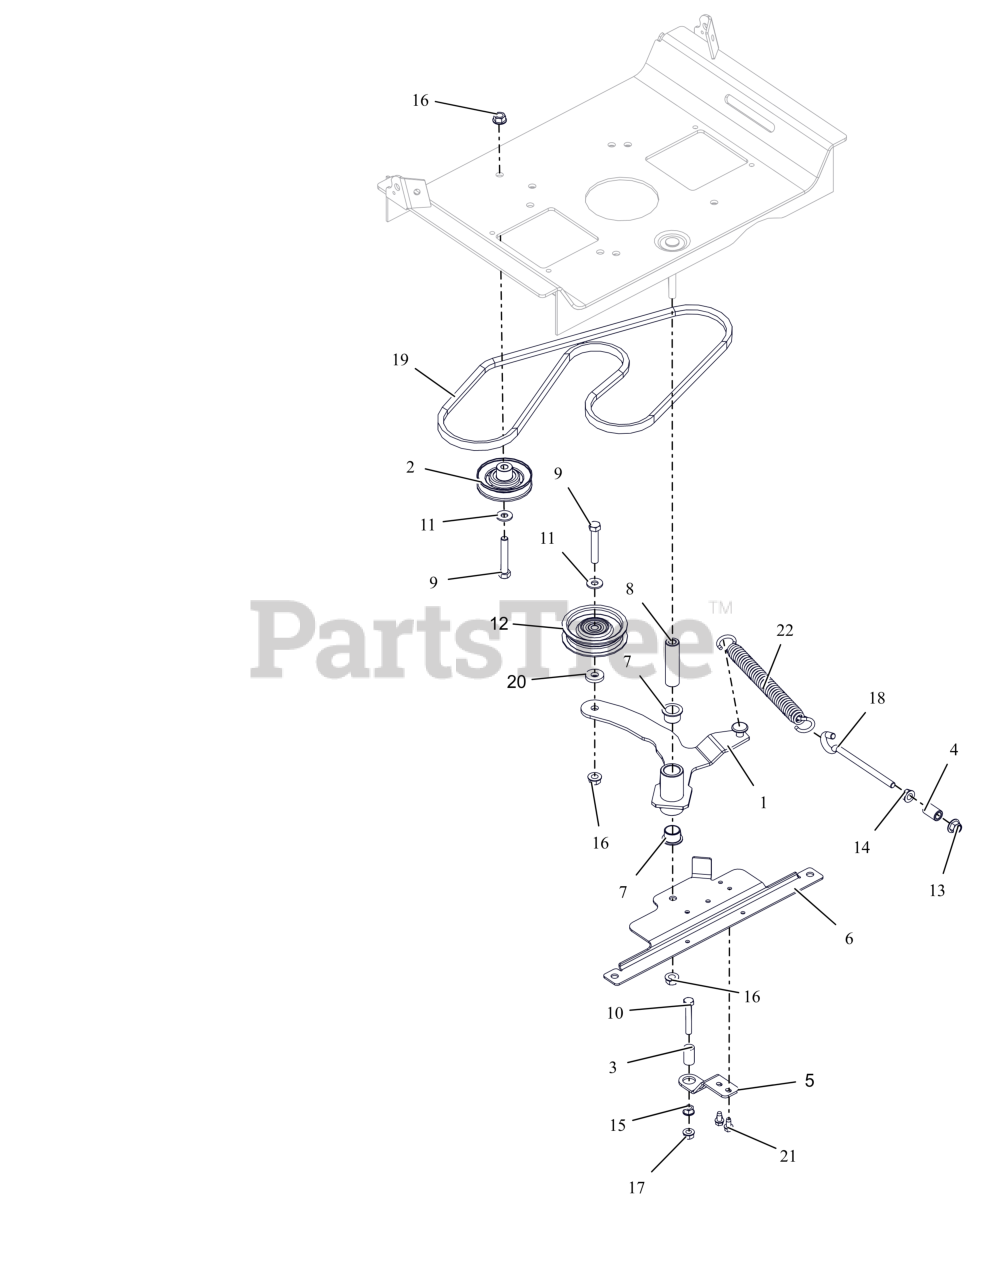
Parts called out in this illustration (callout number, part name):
1	WLDMT,GRD DRIVE IDLER ARM-LGR
2	IDLER, V-3.000 OD
3	SPACER, RUBBER 5/16 IDX1.0 LG
4	SPACER, .375X.625X.970 (PM)
5	BRKT, CLUTCH STOP (XL)
6	BRKT-IDLER ATTACHMENT
7	BSHG-FLG 0.75X0.875X.625X1.125
8	BUSHING, SLEEVE .38X.750X2.78
9	BLT,HEX .38-16X2.25 G5 ZCC
10	BLT, HEX .31-18X2.00 G5 ZCC
11	WSHR,FLT .375X.875X.083 ZCC
12	SHEAVE, IDLER -V .38 x 4.00
13	NUT,NYL-FLG .38-16 GF ZCC
14	NUT, SPNLK-FLG .38-16 G5 ZCC
15	NUT,SPNLK-FLG .31-18 G5 ZCC
16	NUT-LK-TOP-FLG .38-16 ZC120
17	NUT-LK-TOP-FLG .312-18 GF ZCC
18	BOLT,.38-16 X 4.25-.62 DIA EYE
19	V-BELT, A-RAW EDGE
20	WSHR, FLT .406X1.00X.188 ZCC
21	SCR-TAP .25-20X.50 HWH ZCC
22	SPRING, EXTENSION
